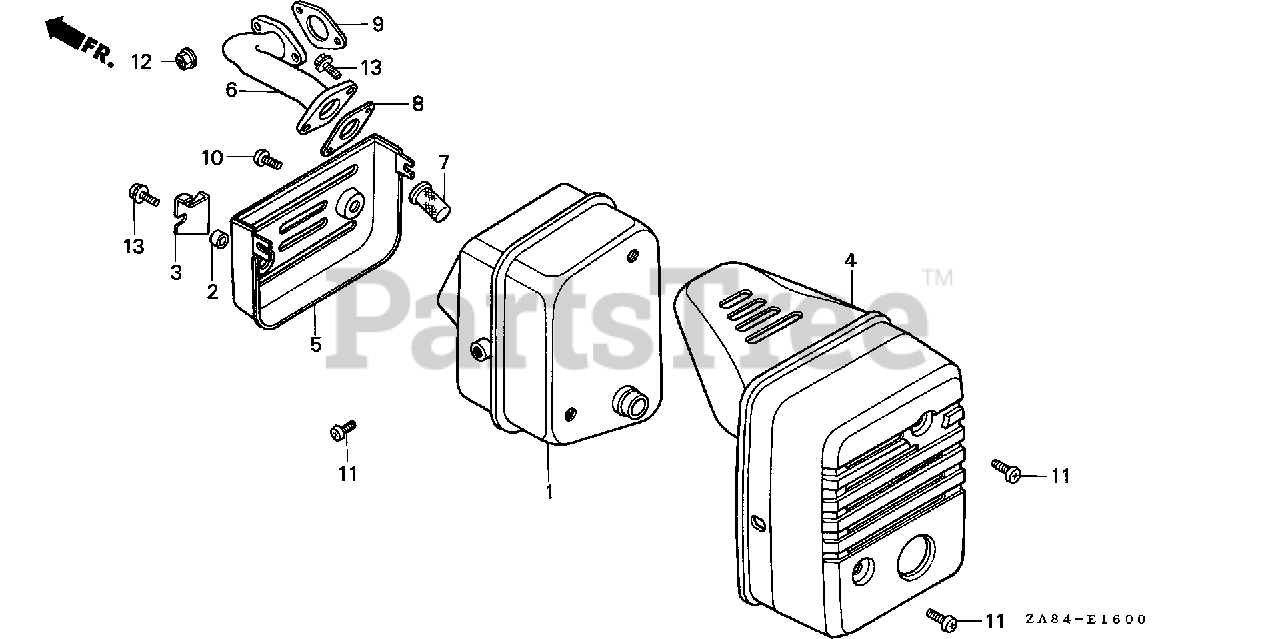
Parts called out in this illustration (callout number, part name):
1	MUFFLER
2	COLLAR, STAY
3	STAY, MUFFLER
4	PROTECTOR, MUFFLER
5	SEPARATOR, MUFFLER
7	ARRESTER, SPARK
8	GASKET, MUFFLER
9	GASKET B, MUFFLER
10	SCREW, PAN (6X6)
11	SCREW, PAN (6X6)
12	NUT, FLANGE (6MM)
13	BOLT, FLANGE (6X16)
